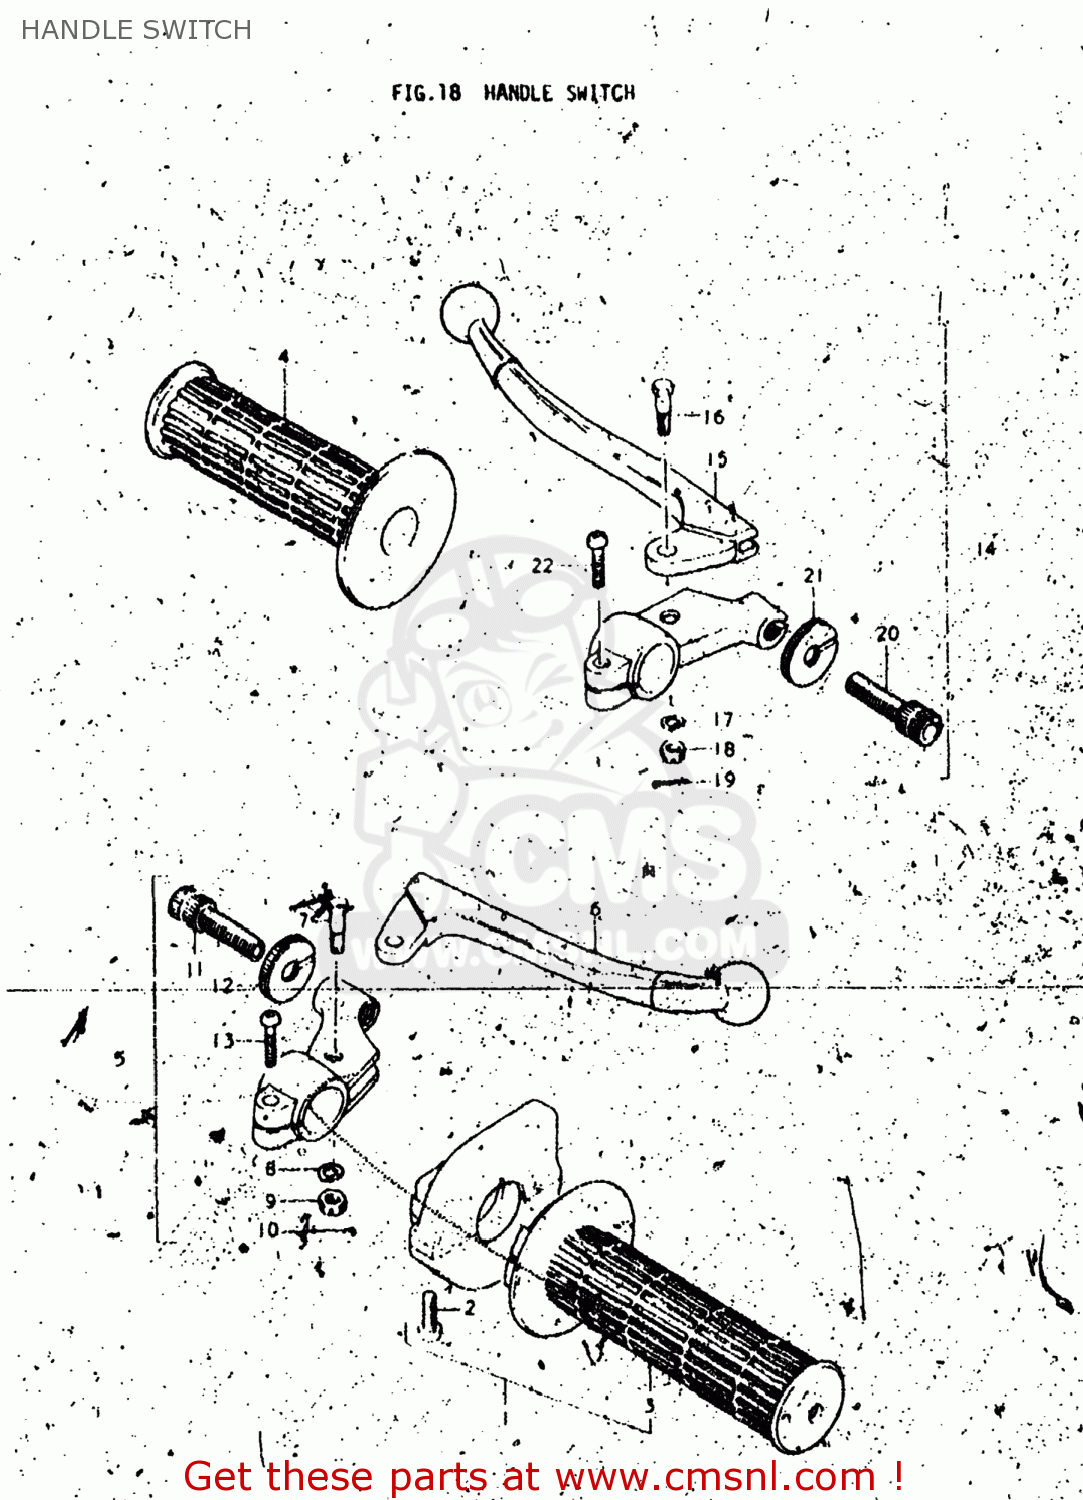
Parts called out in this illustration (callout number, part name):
1	CASE ASSEMBLY,THROTTLE
2	SCREW
3	GRIP,THROTTLE
4	GRIP,LEFT
5	LEVER ASSEMBLY,BRAKE
6	LEVER,BRAKE
7	BOLT,LEVER
8	LOCK WASHER
9	NUT,LEVER FITTNG
10	COTTER PIN
11	ADJUSTER,CABLE
12	NUT,CABLE ADJUSTER
13	SCREW
14	LEVER ASSEMBLY,CLUTCH
15	LEVER,CLUTCH
16	BOLT,LEVER
17	LOCK WASHER
18	NUT,LEVER FITTNG
19	COTTER PIN
20	ADJUSTER,CABLE
21	NUT,CABLE ADJUSTER
22	BOLT
